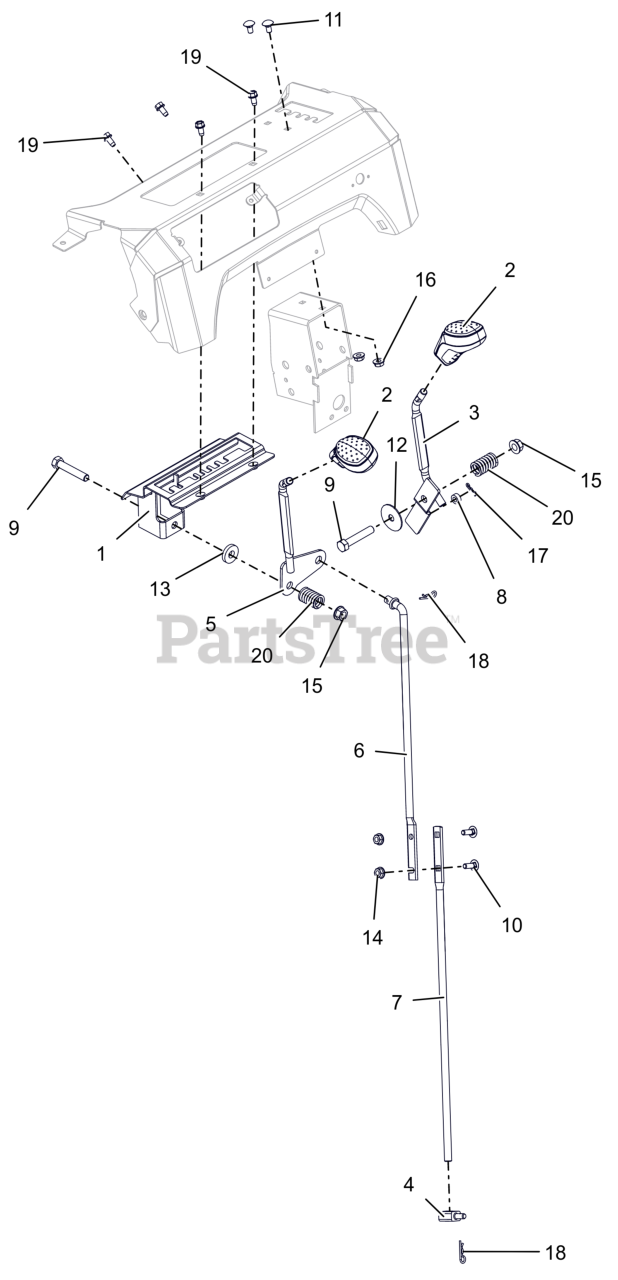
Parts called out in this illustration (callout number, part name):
1	WELDMENT, DETENT PLATE-COMPACT
2	KNOB, CONTROL, DASH
3	WELDMENT,SM DASH DEFL CONTROL
4	PIVOT,SHIFT ROD .375-16(TRUNN)
5	LEVER, CONTROL-SHIFT(WELDMENT)
6	ROD, SHIFT - UPPER
7	ROD, SHIFT-LOWER (SM DASH DLX)
8	BSHG-SLV .265X.500X.219
9	BLT,HEX .38-16X2.00 G5 ZCC
10	BLT, RHSN .25-20X.750 G5 ZCC
11	BLT, RHSN .25-20X.500 G5 ZCC
12	WSHR,FLT .380X1.50X.062 ZCC
13	WSHR, FLT .406X1.00X.188 ZCC
14	NUT-LK-CTR-FLG .25-20 ZC120
15	NUT-LK-TOP-FLG .38-16 ZC120
16	NUT-LK-TOP-FLG .250-20 GF ZCC
17	PIN, HAIR #178 .06X.77 ZCC
18	PIN, HAIR #213 .08X1.19 ZCC
19	SCR-TAP .25-20X.50 HWH ZCC
20	SG-COMP .125X.781X1.250
